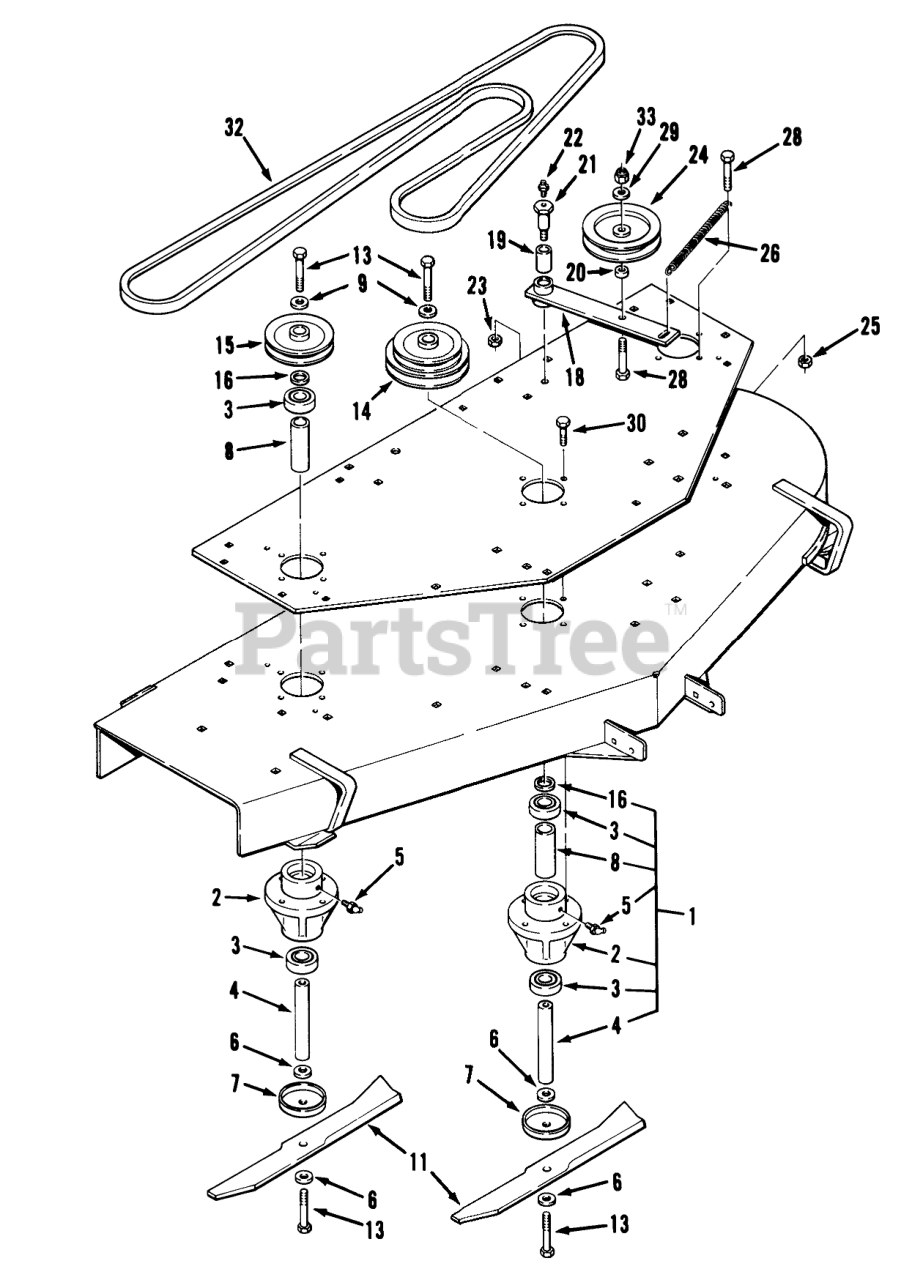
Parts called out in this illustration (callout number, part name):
1	S/A COMM MWR SPINDLE
2	HOUSING-SPINDLE
3	BEARING-BALL
4	SHAFT-SPINDLE
5	FITTING-GREASE
6	WASHER-SPECIAL
7	CUP-SPINDLE
9	WASHER-SPECIAL
11	BLADE
13	Bolt
14	Pulley-Center Spindle
15	PULLEY-OUTER
16	SPACER
18	Idler Arm (includes Bushing)
19	BUSHING
20	SPACER
21	BOLT-SHOULDER
22	FITTING-GREASE, 90 DEG
23	NUT
24	PULLEY-IDLER
25	Nut
26	SPRING-EXTENSION
28	BOLT
29	Washer
30	BOLT
32	BELT-V
33	Nut
